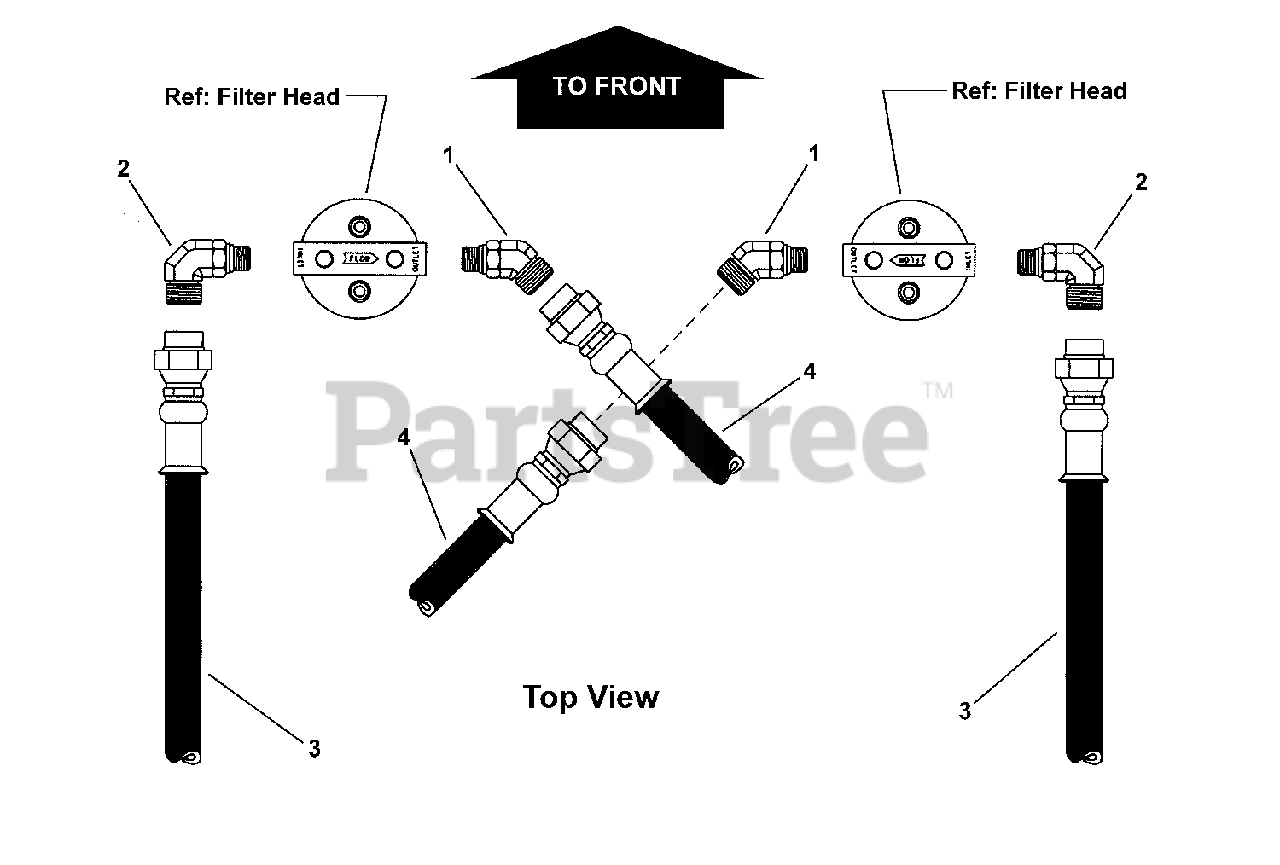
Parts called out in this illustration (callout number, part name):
1	CONNECTOR, 90 Degree Hydraulic (Parker # 8-6 C5OLO-S)
2	CONNECTOR, Hydraulic (Parker #8-6 V 50L0-S)
3	HOSE, 18-1/2" (Parker R836BKJCJ9090808-18.5)
4	HOSE, 12-1/4" (Parker # R836BKJ9NR080008-12.5)
